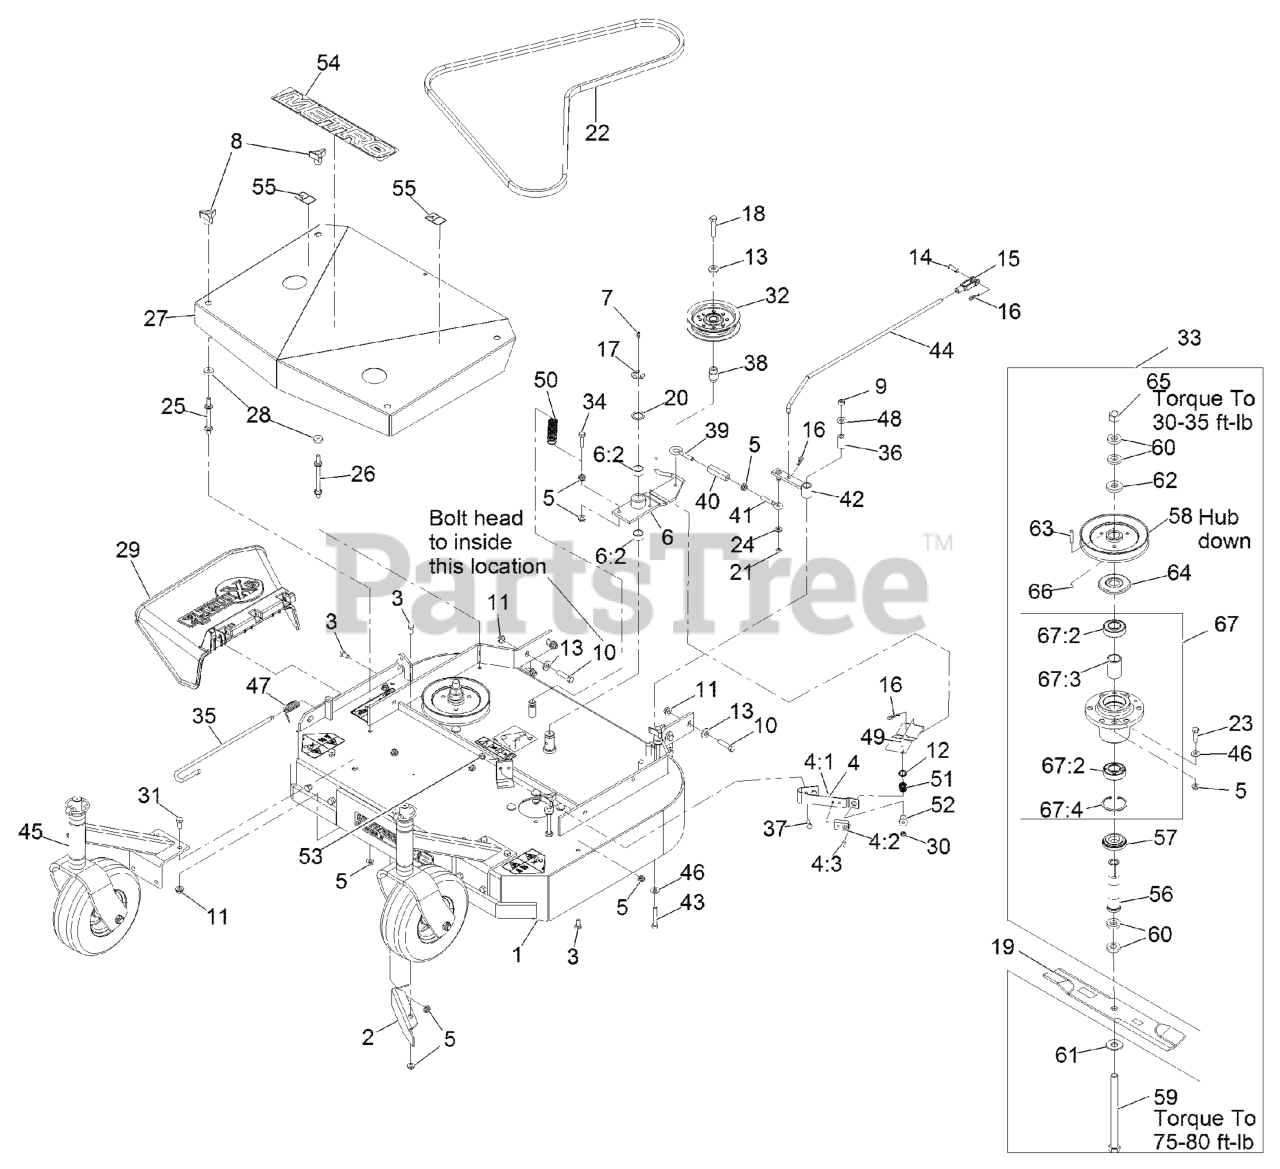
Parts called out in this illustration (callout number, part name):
1	ASM, DECK 32 RIGID
2	BAFFLE-DOGLEG
3	SCREW-HH
4	PAD AND SPRING ASM
6	IDLER ARM ASM
6:2	SLEEVE-BEARING
7	FITTING-GREASE
8	KNOB-3 PRONG
9	NUT-LOCK, NI
10	SCREW-HH
11	NUT-HHF, WHIZ
12	RING-PUSH ON
13	WASHER-BELLEVILLE
14	PIN-CLEVIS
15	YOKE-ADJUSTABLE
16	PIN-COTTER
17	RING-RETAINING, EXT
18	SCREW-HH
20	WASHER-SPINDLE
21	RING-RETAINING, EXT
22	BELT,BLADE METRO 32
23	SCREW-HH
24	WASHER-PLAIN
25	STUD-SHIELD, BELT (SHORT)
26	STUD-SHIELD, BELT (LONG)
27	ASM,SHIELD W/DECALS 32 ME
29	CHUTE DEFLECTOR XRK M056
30	NUT-LOCK, NI
31	SCREW-HH
33	ASM, CUTTER HOUSING OUTER
34	SCREW-HH, SPECIAL
35	PIN-CHUTE
36	TUBE-PIVOT
37	SCREW-HH
38	BUSHING-ENGAGEMENT
39	EYEBOLT-THREAD, LH
40	BODY-TURNBUCKLE
41	EYEBOLT-THREAD, RH
42	ARM-ASSIST, 32/36
43	SCREW-HH
44	ARM-ASSIST, LINKAGE
45	ASM,CASTER/MOUNT
46	WASHER-SPRING
47	SPRING, TORSION
48	WASHER-FLAT
49	ROD-BRAKE
50	SPRING-EXTENSION
51	SPRING-COMPRESSION
52	SPACER-FLANGED
53	NUT-LOCK, NI
54	Decal-Metro
55	DECAL-WARNING
56	TUBE-SPINDLE, SHORT
57	SPACER-GUARD, BOTTOM
58	SHEAVE
59	SCREW-CAP, HH
61	WASHER-SPRING
62	WASHER-RETAINER, SHEAVE
64	GUARD-BEARING, TOP
65	NUT-HEX
66	SETSCREW
67	KIT, CUTTER HOUSING
67	BEARING-JACKSHAFT
67:2	SPACER-BEARING
67:3	RING-SNAP
67:4	NUT-LOCK, NI
